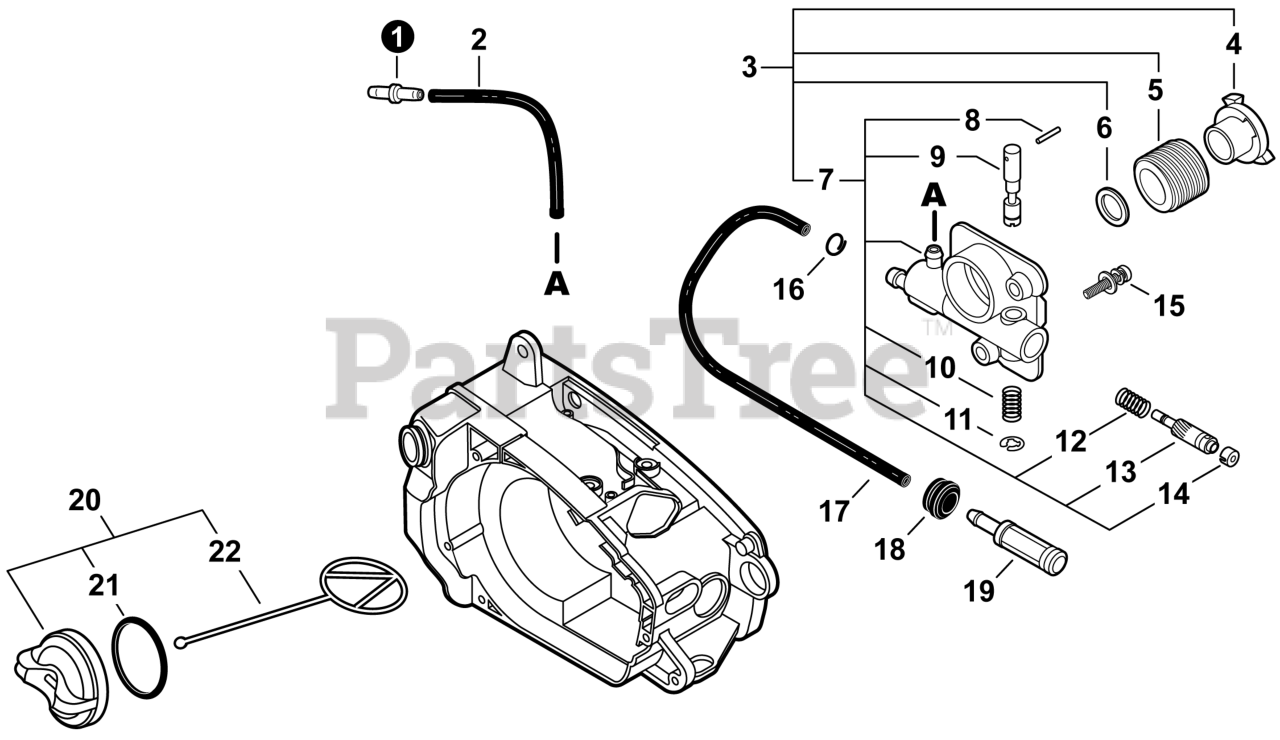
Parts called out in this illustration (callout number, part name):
1	CONNECTOR, PIPE
2	PIPE, 3x6x45 BLACK
3	AUTO-OILER ASSY
4	COLLAR 10
5	GEAR, WORM
6	WASHER 10.5x17.4x1.8
7	AUTO-OILER
8	PIN, SPRING
9	ADJUSTER, OILER
10	SPRING
11	E-RING
12	SPRING
13	PLUNGER ASSY
14	CAP, OIL PUMP
15	SCREW 4x12
16	CLIP 6.5 MM
17	PIPE, FUEL 3x6x150
19	FILTER, OIL
20	CAP ASSY - BLACK
21	O-RING 18
22	CONNECTOR, CAP L= 60 MM
